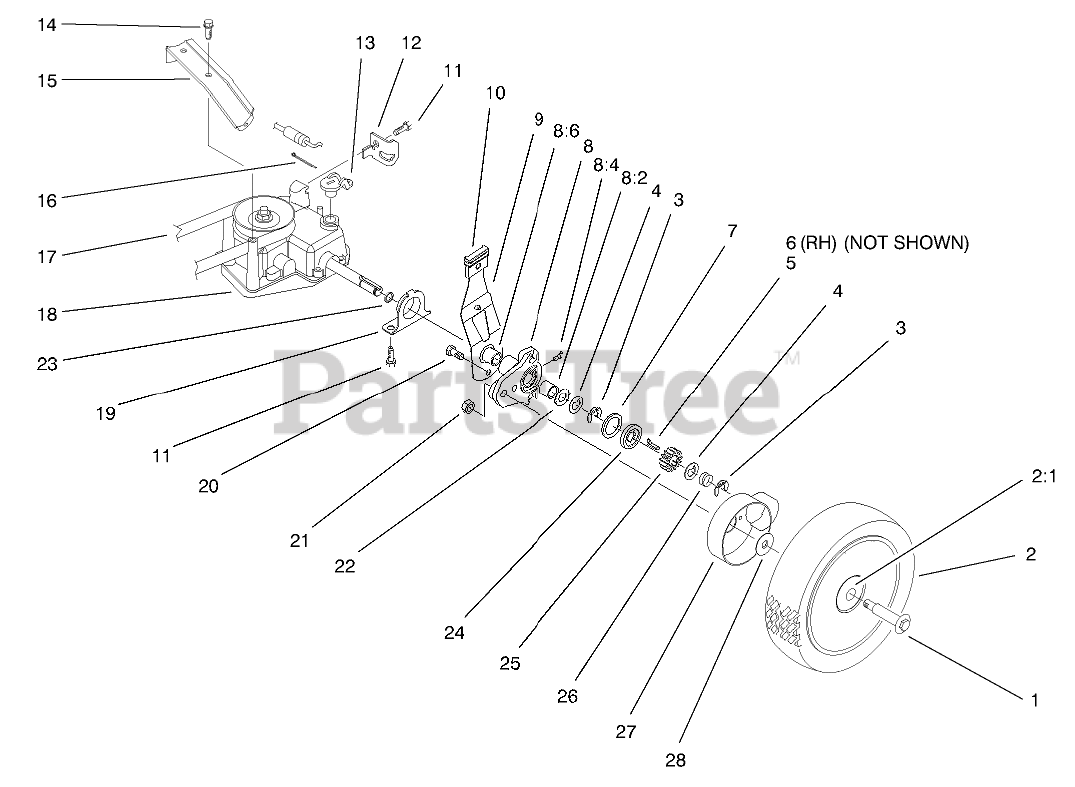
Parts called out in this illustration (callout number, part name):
1	WHEEL BOLT
2	WHL & TIRE ASSEMBLY
2:1	BUSHING
3	RING-CLIP, LOCKING
4	WASHER-THRUST, KEYED
5	KEY-ROCKING, LH
6	KEY-ROCKING, RH
7	RING-FRICTION
8	PIVOT ARM ASM
8:2	BEARING-ROLLER
8:4	FITTING-GREASE
8:6	BUSHING
9	SPRING ARM ASM
10	KNOB-ARM
11	SCREW-HWHTF
12	RETAINER-CABLE
13	LEVER-SHIFT
14	SCREW-HWHTF
15	Bracket-BeltGuide
16	PIN-COTTER
17	V-BELT
18	GEARCASE ASM
19	CAP-END
20	SCREW-HSH, THREAD FORMING
21	NUT-LOCK
22	WASHER-ARM, PIVOT
23	O-RING
24	WASHER-CLUTCH
25	GEAR-PINION
26	SPRING-COMPRESSION
27	COVER-WHEEL
28	SPACER-COVER, WHEEL
